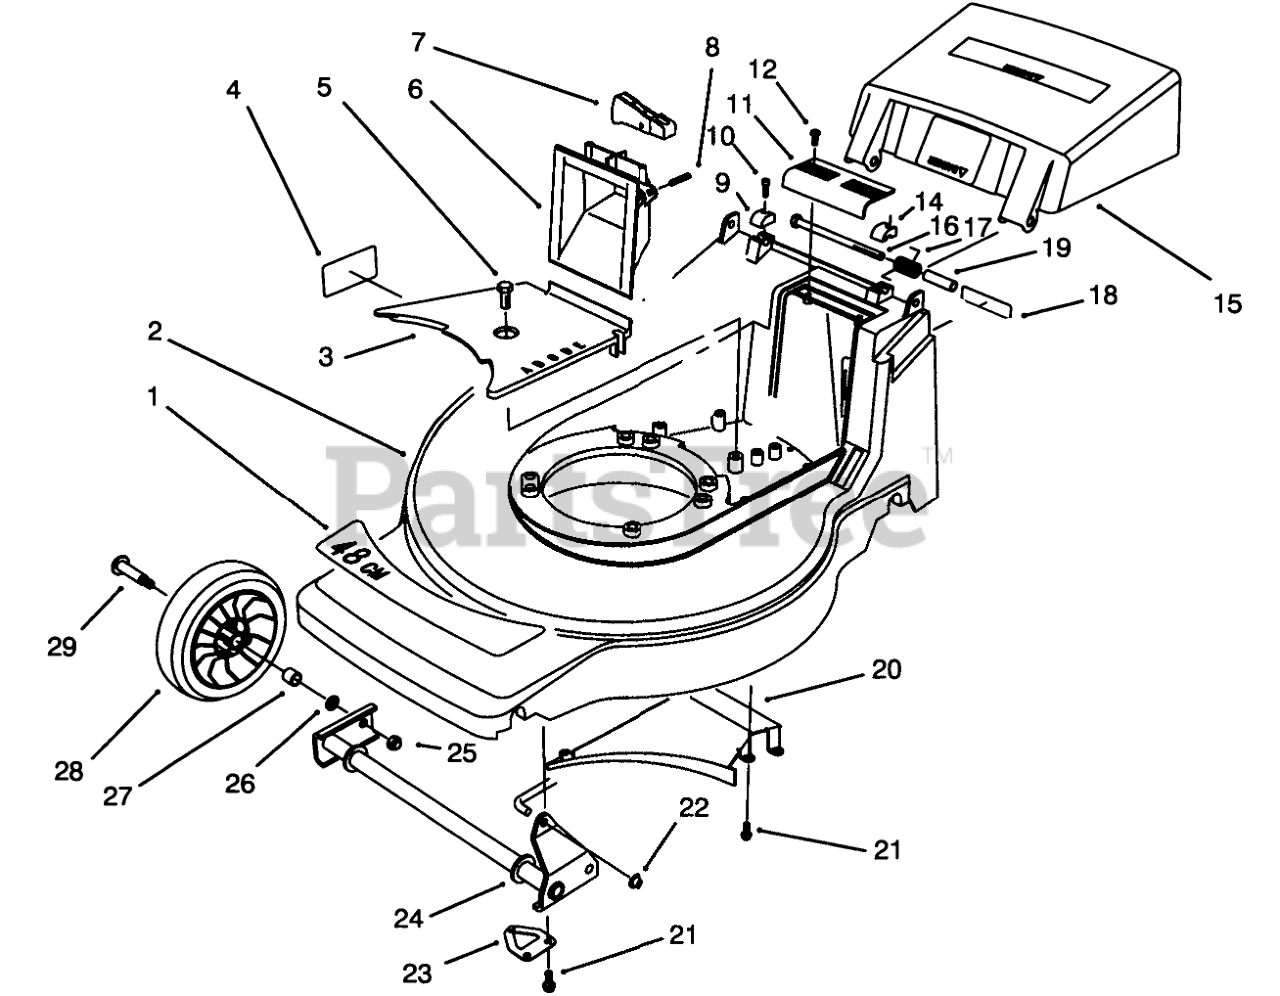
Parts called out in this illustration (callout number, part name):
1	DECAL - DECK 48 CM
2	Housing-48cm (Incl. Ref. #4)
3	BELT COVER
4	DECAL - DIN/DANGER
5	SCREW-HWHTF
6	GRIP - LOWER
7	TRIGGER - HOC
8	PIN-SPIRAL
9	CAP-HINGE BOLT, RH
10	SCREW-HSH
11	GRIP-UPPER
12	SCREW-PPH, PLASTITE
14	CAP-HINGE BOLT, LH
15	Door Discharge
16	SCREW-HH
17	SPRING-DOOR
18	DECAL FRENCH REGUL.
19	SPACER-DOOR
20	Ramp-Discharge
21	SCREW-HWH
22	NUT-PUSH
23	SHAFT RETAINER ASM
24	FRONT PIVOT WA
25	NUT-HEX
26	WASHER
27	BUSHING
28	Wheel & Tire Assembly (Incl. Ref. #27)
29	BOLT-WHEEL
